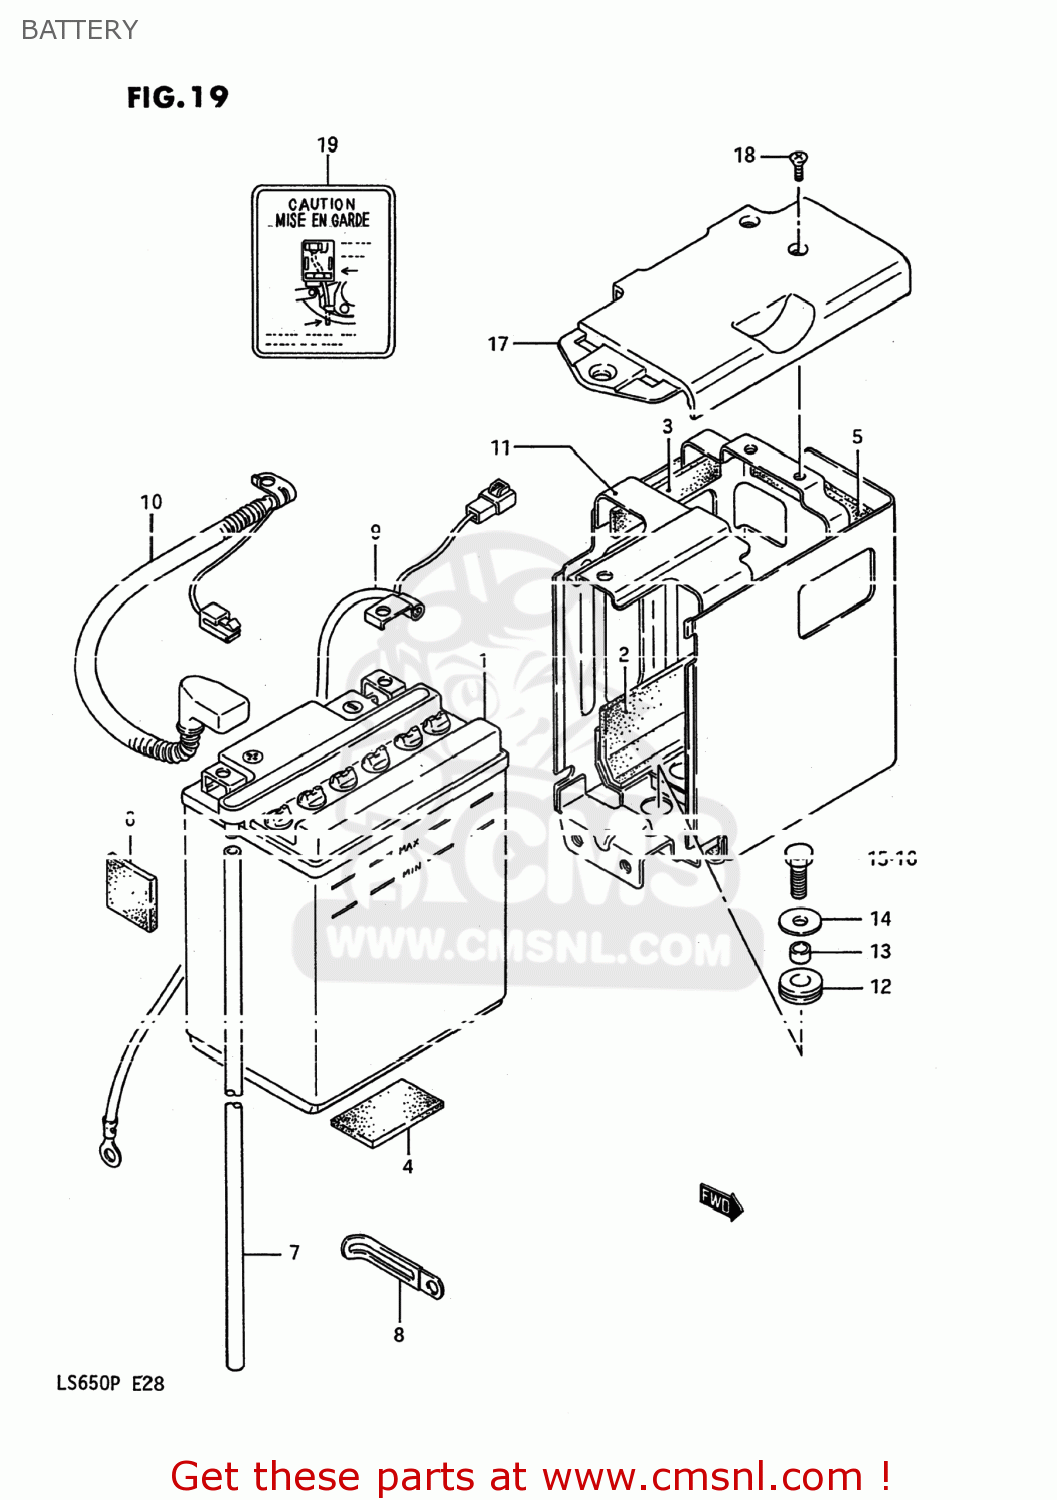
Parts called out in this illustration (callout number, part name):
1	BATTERY(YB14L-B2,12V14.7AH)
2	PROTECTOR(170X95X3.0)
3	PROTECTOR(170X95X3.0)
4	PROTECTOR(170X95X3.0)
5	PROTECTOR(20X90)X2
6	PROTECTOR,BATTERY
7	HOSE,BATTERY EXHAUST
8	CLAMP
9	WIRE,BATTERY MINUS
10	WIRE,BATTERY PLUS LEAD
11	HOLDER COMP,BATTERY
12	CUSHION
13	SPACER
14	WASHER
15	SCREW
16	SCREW(6X20)
17	COVER,BATTERY
18	SCREW
19	PLATE,BATTERY CAUTION
